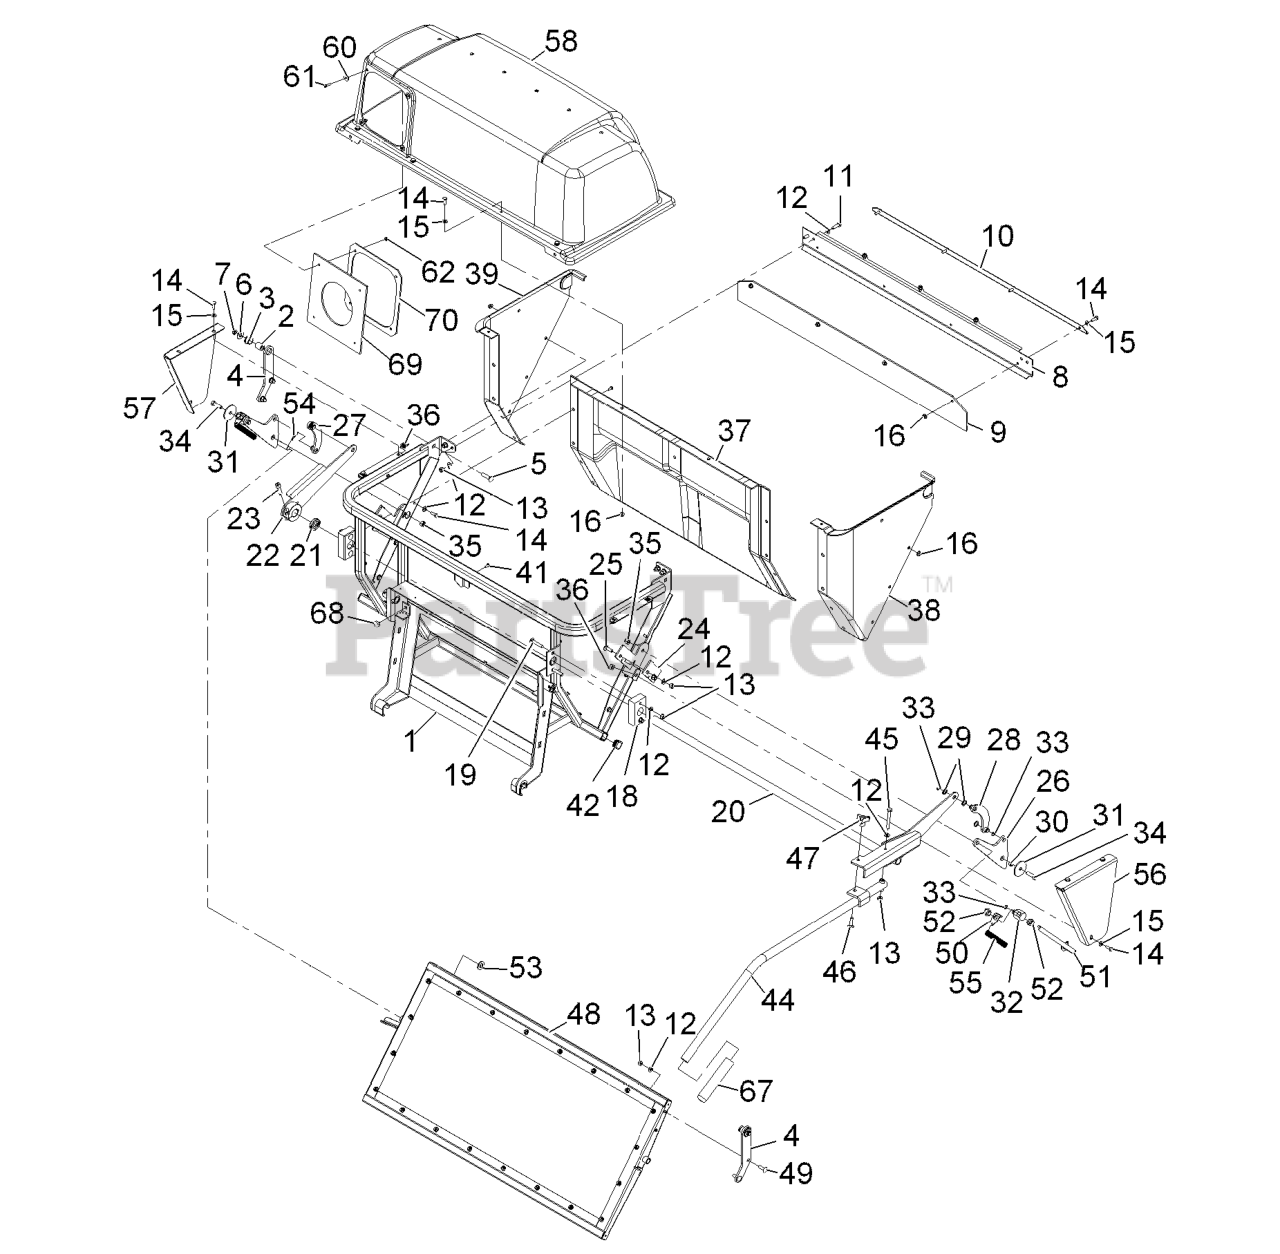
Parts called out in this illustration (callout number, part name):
1	FRAME ASM
2	PIN-PIVOT, HINGE
3	BEARING
4	PLATE-HINGE
5	SCREW-CARR
6	WASHER-FLAT
8	PLATE-REAR
9	SEAL-DOOR
10	STRAP-HOLD DOWN
11	SCREW-HH
12	WASHER-PLAIN
13	NUT-LOCK, NI
14	SCREW-HH
15	WASHER-FLAT
18	BEARING
19	BOLT-CAR
20	BELLCRANK
21	SHAFT-COLLAR
23	SCREW-HSH
24	STOP-LINKAGE
25	BOLT-CARR
26	ARM-LINKAGE, DOOR
27	LINK-RH
28	LINK-LH
29	WASHER-NYLON
30	BEARING-LINKAGE, PIVOT
32	TRUNNION-LINK
33	RING-RETAINING
34	SCREW-HH
35	NUT-LOCK, NI
36	Nut-Retainer-Panel 1/4-20
37	PANEL-BAGGER
38	PANEL-BAGGER, LH
39	PANEL-BAGGER, RH
41	RIVET-BLIND
44	HANDLE-QD7
45	SCREW-HH
46	Bolt-Carriage 5/16-18 X 1 1/4
47	KNOB-3 PRONG
48	Asm, Door
49	SCREW-CARR
50	ANCHOR-SPRING
51	LINK-DOOR
52	NUT-HEX
53	WASHER-FLAT
54	PIN-COTTER
58	ASM, HOOD
60	WASHER-FLAT
61	SCREW-PPH
62	NUT-LOCK, NI
67	HANDLE-GRIP
69	SEAL-CHUTE
70	CLAMP-SEAL
